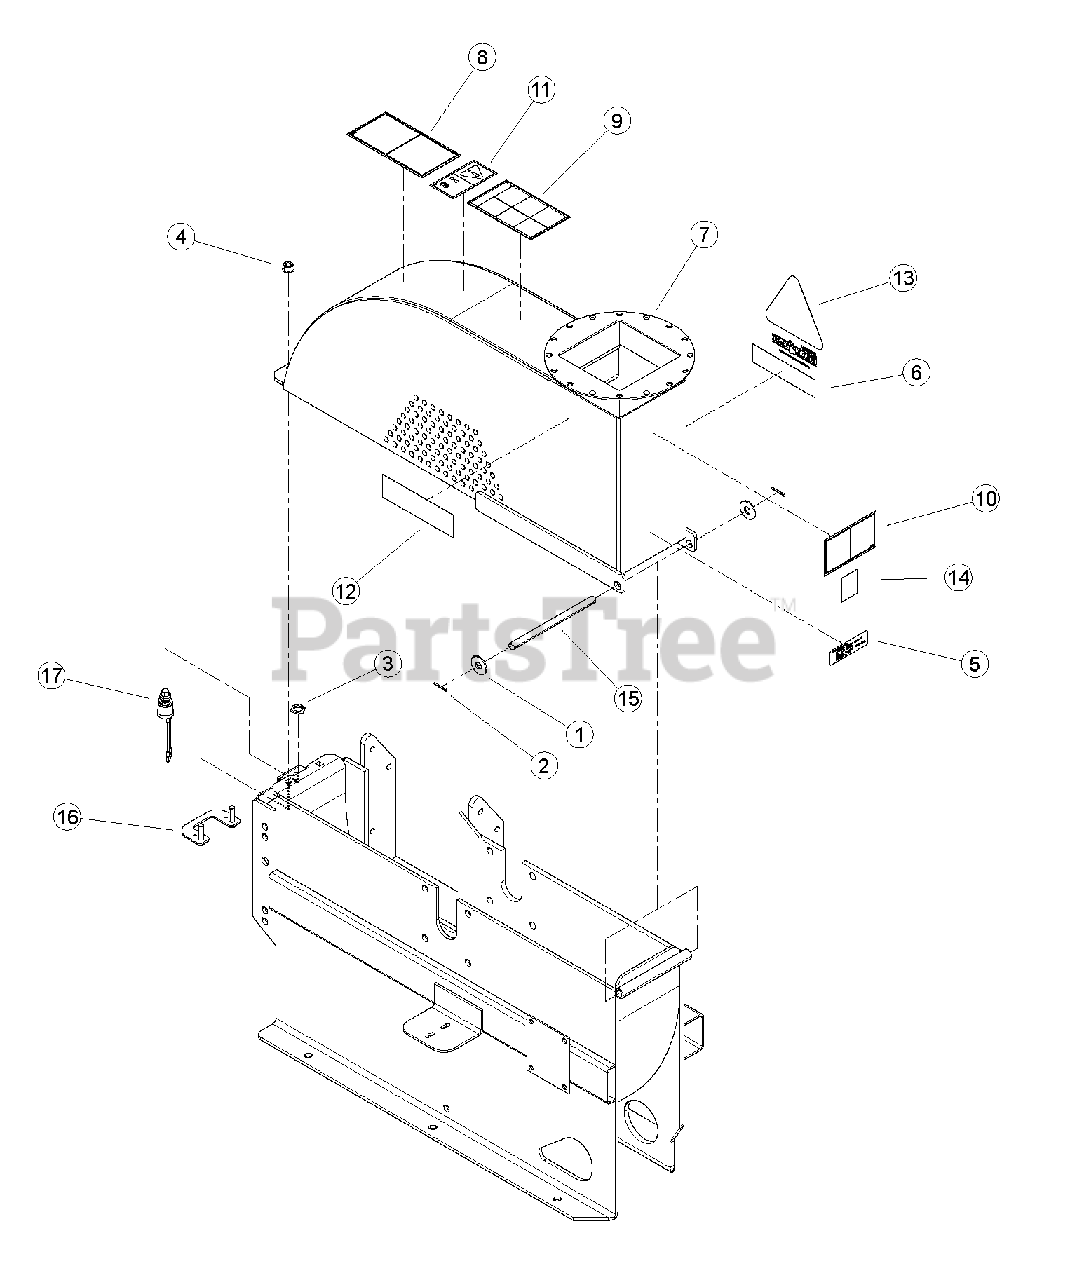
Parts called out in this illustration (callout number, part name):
1	WASHER, 1/2" FLAT ZP
2	PIN, 1/8 X 1.00 ZP COTTER
3	NUT, 5/8-32 JAM
4	NUT, 3/8-16 NYLOCK FLANGE
5	DECAL, ATLANTIC BRIDGE LTD INFO (CE COMPLIANT ONLY)
6	DECAL, MODEL CH8993H
7	ASSEMBLY, CHIPPER COVER W/DECALS
8	DECAL, KNIFE ACCESS ISO
9	DECAL, OPERATING INSTRUCTIONS ISO
10	DECAL, DISCHARGE ISO
11	DECAL, MAINTENANCE ISO
12	DECAL, ECHO BEARCAT 6.82 X 1.90
13	DECAL, CHIP IT
14	DECAL, ECHO BEARCAT QR CODE
15	SHAFT, CHIPPER TOP PIVOT
16	WELDMENT, CHIPPER HOUSING ACCESS
17	ASSEMBLY, SEALED SWITCH
